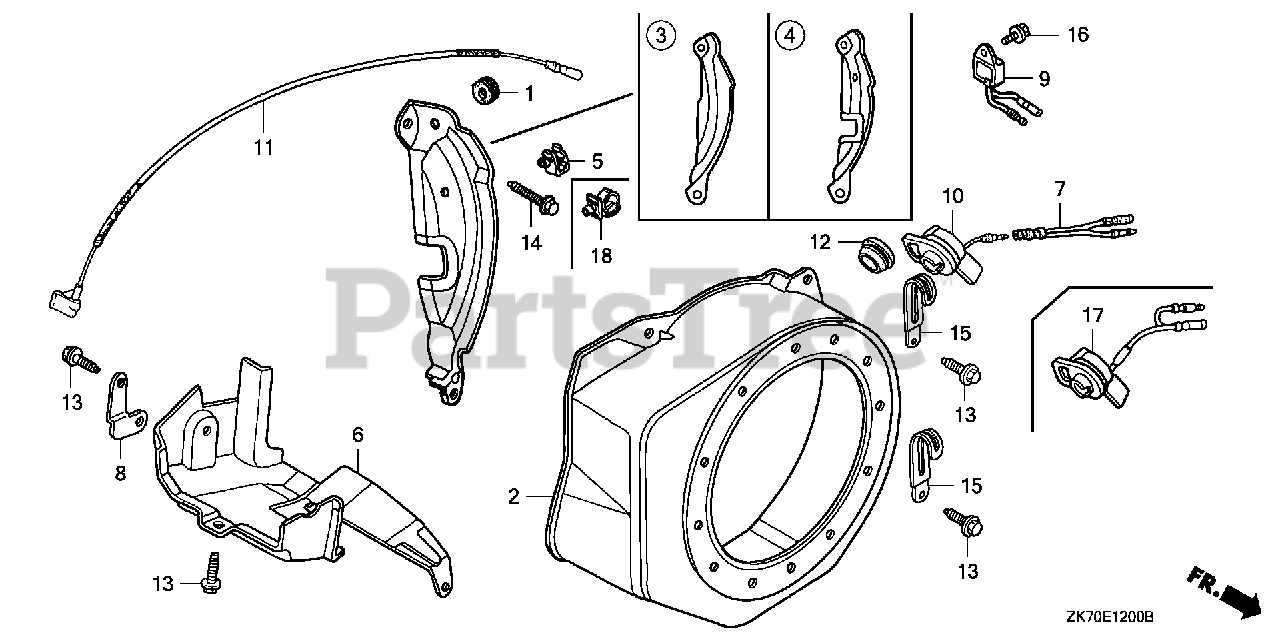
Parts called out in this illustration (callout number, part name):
1	GROMMET, ADJUSTING COVER
2	COVER, FAN *R280* (POWER RED)
3	PLATE, SIDE (OIL ALERT)
9	ALERT UNIT, OIL
10	SWITCH ASSY., ENGINE STOP
11	WIRE, STOP SWITCH (370MM)
13	BOLT, FLANGE (6X12) (CT200)
14	BOLT, FLANGE (6X20) (CT200)
16	BOLT, FLANGE (6X8)
18	CLIP, HARNESS
